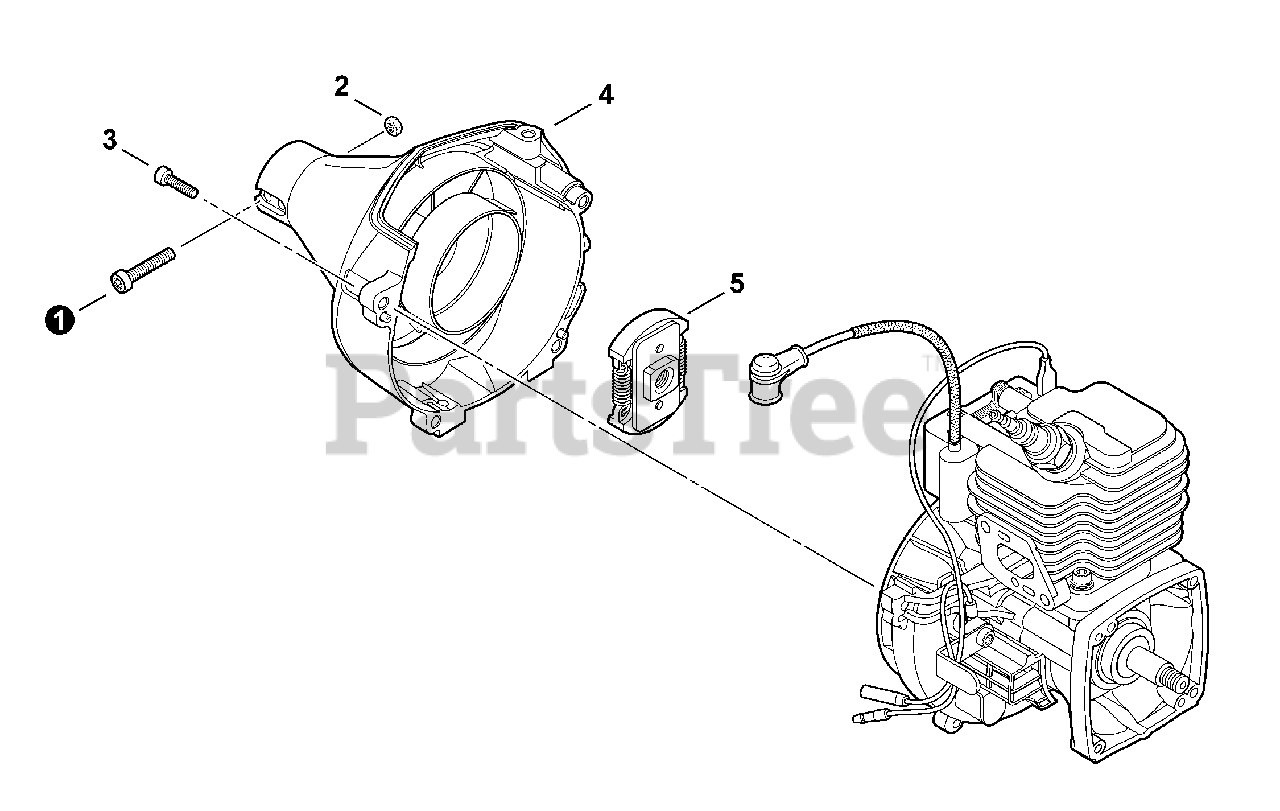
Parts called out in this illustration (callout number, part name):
1	BOLT, TORX 5×25
2	NUT M5
3	BOLT, TORX 4×16
4	FAN CASE ASSY
5	CLUTCH ASSY
